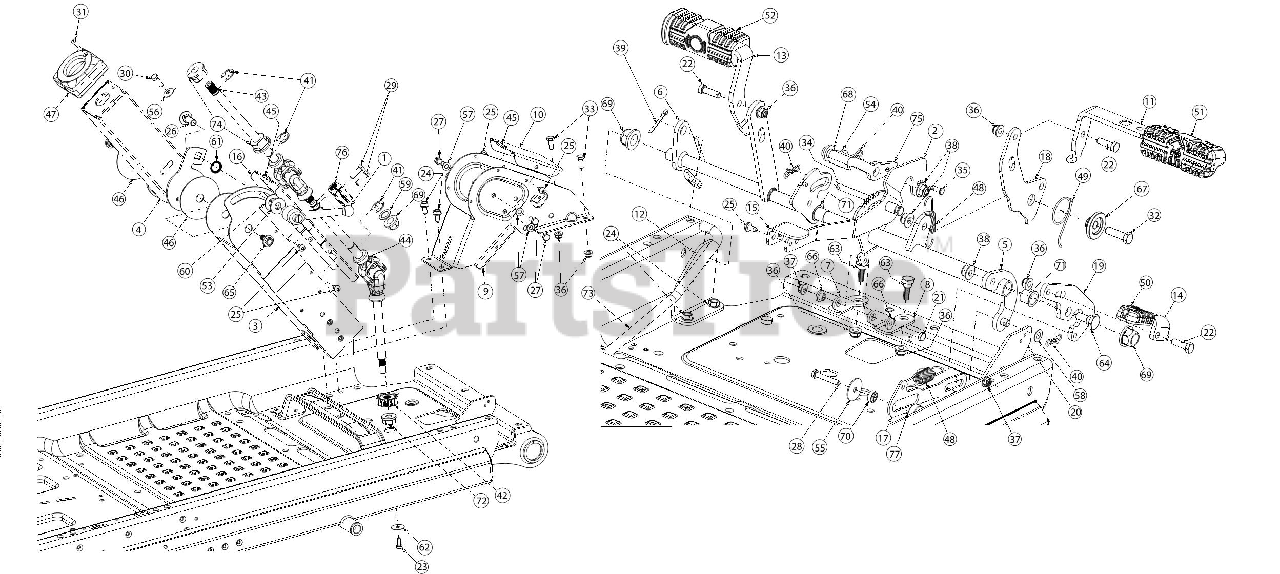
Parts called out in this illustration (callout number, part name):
1	LEVER - ADJ STEERING
2	CRUISE/BRAKE ARM
3	LOWER COLUMN ASSEMBLY
4	UPPER PIVOT COLUMN ASSEMBLY
5	DRIVE PEDAL SHAFT ASSEMBLY
6	BRAKE SHAFT ASSEMBLY
7	PEDAL SHAFT BRACKET (LH)
8	PEDAL SHAFT BRACKET (RH)
9	LOWER STEERING COLUMN
10	LOWER COLUMN COVER
11	FORWARD DRIVE PEDAL
12	BEARING SUPPORT BRACKET
14	REVERSE DRIVE PEDAL
15	TILT STEERING PEDAL
16	STEERING COLUMN COVER
17	NEUTRAL RETURN LINK
18	FORWARD PEDAL BRACKET
19	REVERSE PEDAL PIVOT PLATE
20	PEDAL BRACKET (RH)
21	HEX SCREW 1/4-20 X 1.25
22	SCREW 5/16-18 X 1.0 GR5
23	SCREW 1/4-20 X .62 SPEC GR5
24	SCREW 5/16-18 X .750
25	SCREW 1/4-20 X .5
26	CARRIAGE BOLT 1/2-13 X 1.25 GR5
27	SCREW 5/16-18 X .62 GR5
28	SCREW 1/4-20 X 1.50 GR.5
29	SCREW 5/16-18 X 1.00 GR5
30	SCREW 5/16-24 X .875 GR5
31	SCREW #10-16 X 1.25
32	SCREW 3/8-16 X 1.25 GR5
33	SCREW 5/16-18 X .75 GR5
34	CLEVIS PIN 5/16 X 4.135
35	CLEVIS PIN .224 X .625
36	FLANGE LOCK NUT 5/16-18
37	FLANGE LOCK NUT
39	COTTER PIN-5/32 DIA
40	BOW TIE COTTER PIN 1/4-5/16
41	E-RING
42	STEERING GEAR 14T
43	UPPER STEERING SHAFT
44	LOWER STEERING SHAFT
45	TRIM STRIP
46	COLUMN PLATE
47	STEERING COLUMN COVER
48	EXTENSION SPRING
49	TORSION SPRING
50	REVERSE PEDAL PAD
51	FORWARD PEDAL PAD
52	BRAKE PEDAL PAD
54	FLAT WASHER .535 X .930 X .090
55	FLAT WASHER
56	BELL WASHER .337 X.867 X .057
57	FLAT WASHER
58	WASHER THRUST .375X.70X.030
59	FLAT WASHER
60	FLAT WASHER NYLON 5/8
61	LOCK WASHER
62	FLAT WASHER
63	SHOULDER SCREW .437
64	SHOULDER SCREW
65	SHOULDER SCREW .625X.165X3/8-16
66	SHOULDER SPACER
67	SHOULDER SPACER 1.50X.38X.38
68	SHOULDER SCREW .496X1.44 3/8-16
69	FLANGE BEARING
70	BALL BEARING .25 X .625 SPCL
71	NYLINER BEARING
72	FLANGE BEARING
73	FRONT BRAKE ROD
74	FLANGE BEARING
75	CRUISE LATCH
76	STEERING SHAFT COUPLING
77	SPACER .267X1.00X.36
